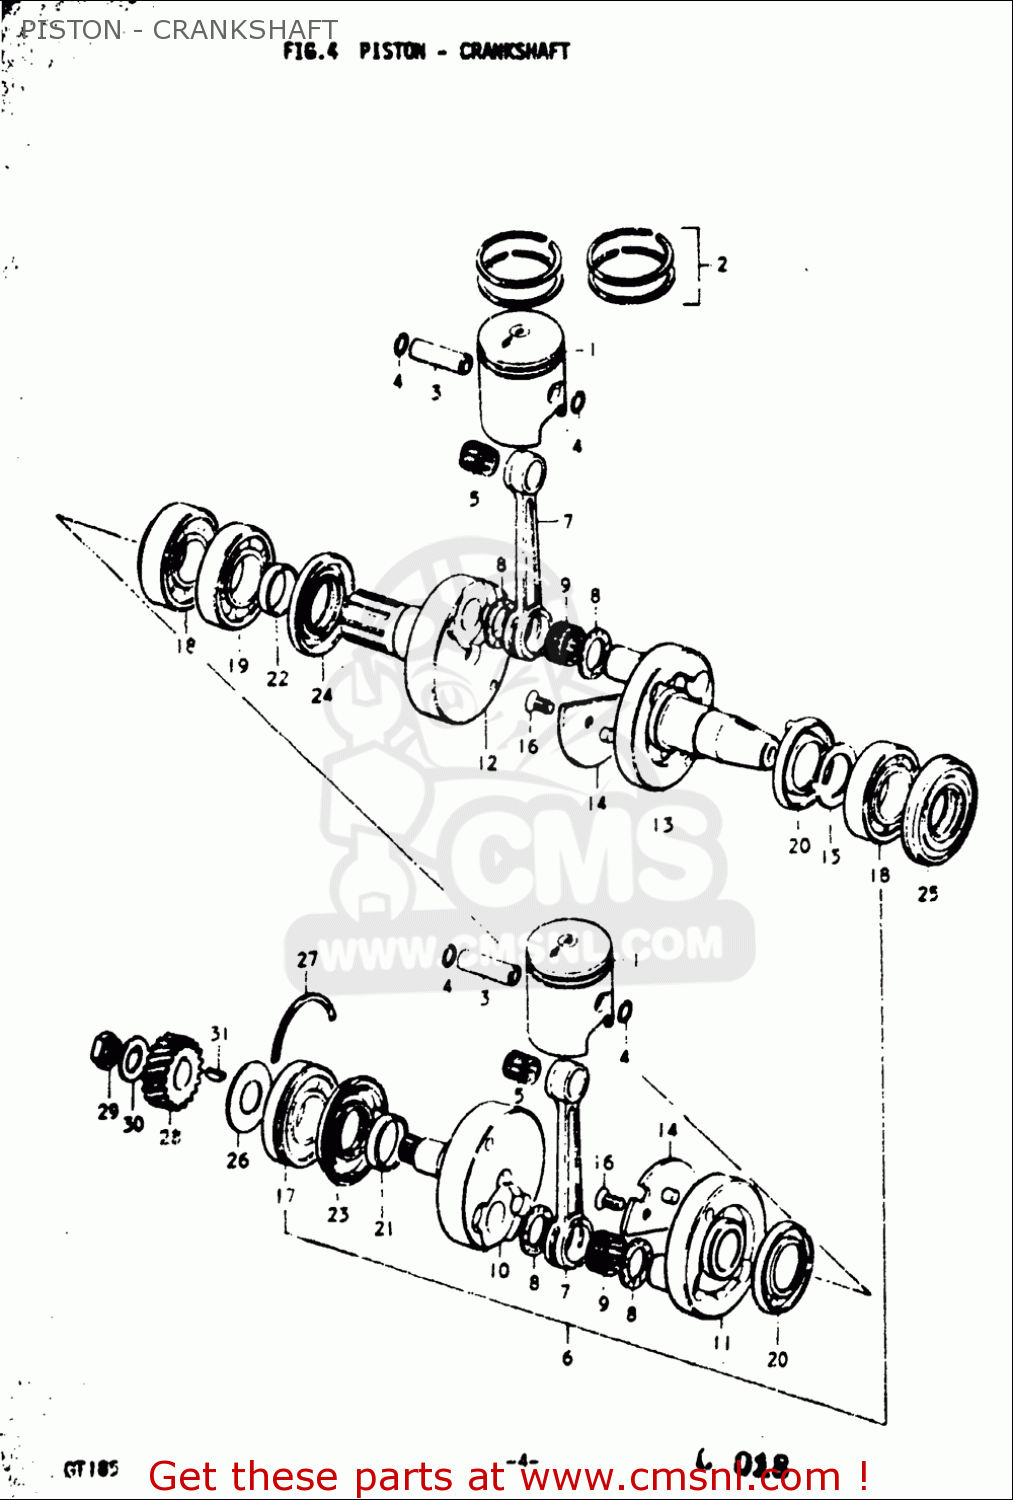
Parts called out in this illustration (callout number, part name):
1	PISTON,STD
2	RING SET,PISTON
3	PIN,PISTON
4	RING,SNAP
5	BEARING(12X16X16)
7	ROD,CONNECTING
8	WASHER(22X35X1)
9	BEARING 22.7X27.8X14
16	SCREW
17	BEARING(25X62X17)
18	BEARING(25X62X17)
21	SPACER(25X32X10.7)
23	SEAL,OIL(32X62X8)
24	SEAL,OIL(37X62X9)
25	SEAL,OIL(25X62X9.9)
26	WASHER(20X48X1)
27	C RING
28	GEAR,PRIMARY DRIVE
29	NUT
30	WASHER
31	KEY
